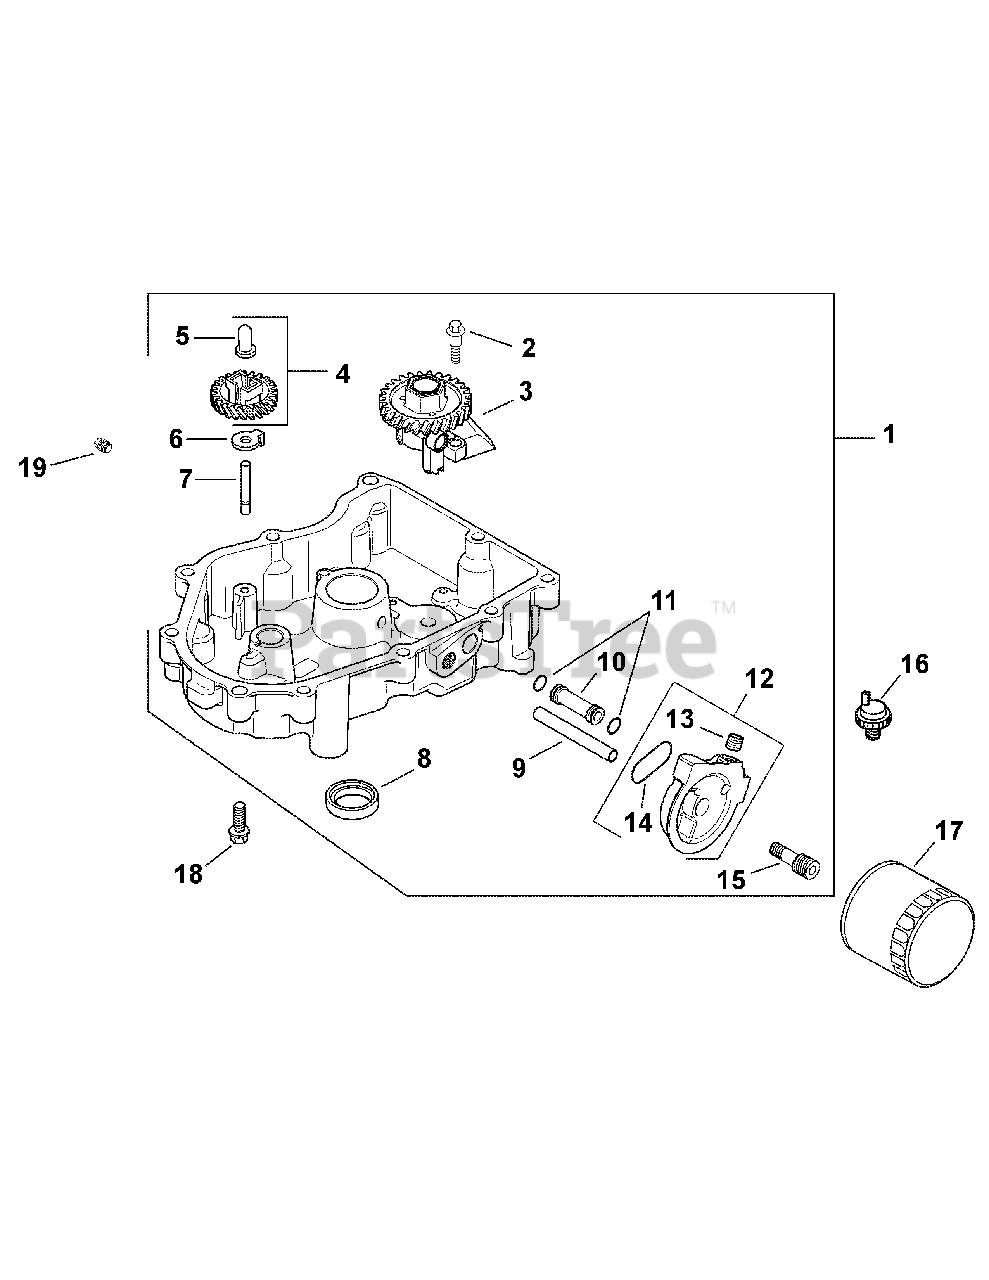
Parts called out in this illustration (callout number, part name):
1	Pan Assembly, Oil (Incl. Ref. 2-15)
2	Screw, Flnge Thrd. Frmng M6 x 1.0 x 26.5
3	Pump Assembly, Oil
4	Kit, Governor Gear w/Pin (Incl. Ref. 5)
5	Pin, Governor Regulating
7	Shaft, Governor Gear
8	Seal, Oil (PTO End)
9	Tube, Oil Feed - Filter to Pan
10	Tube, Oil Feed - Pan to Filter
11	O-Ring, Oil Pick-up
12	Kit, Oil Filter Adapter
13	Plug, Pipe, 1/8
14	O-Ring, Oil Filter Adapter
15	Nipple, Oil Filter
16	Switch, Oil Pressure
18	Screw, Flange, M8 x 1.25 x 45
19	Plug, Sq. Hd. Pipe, 3/8 NOT USED
